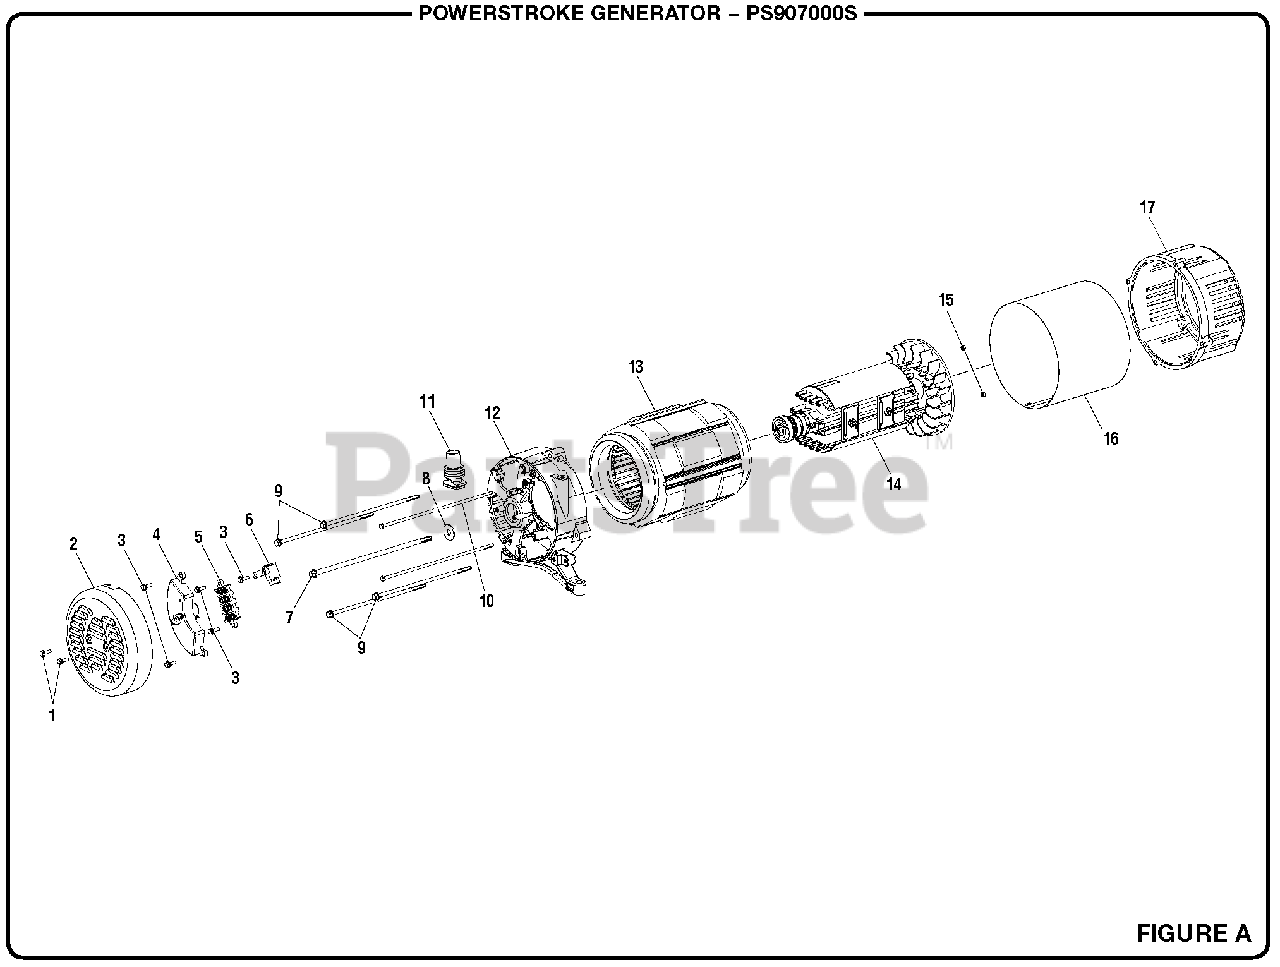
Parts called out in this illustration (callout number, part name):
1	Bolt (M5 x 12 mm, Hex Flange Hd.)
2	Brush Cover
3	Bolt (M5 x 16 mm, Hex Flange Hd.)
4	Automatic Voltage Regulator
5	Terminal Block
6	Brush Assembly
7	Rotor Bolt (5/16-24 x 260 mm, Hex Flange Hd.)
8	Washer (ID10.5 x OD25 x 2t)
9	Stator Bolt (M6 x 216 mm, Hex Flange Hd.)
10	Bolt (M5 x 245 mm, Hex Hd.)
11	Rubber Boot
12	Bearing Housing
13	Stator Assembly
14	Rotor Assembly
15	Hex Nut (M5)
16	Generator Head Cover
17	Engine Adaptor
